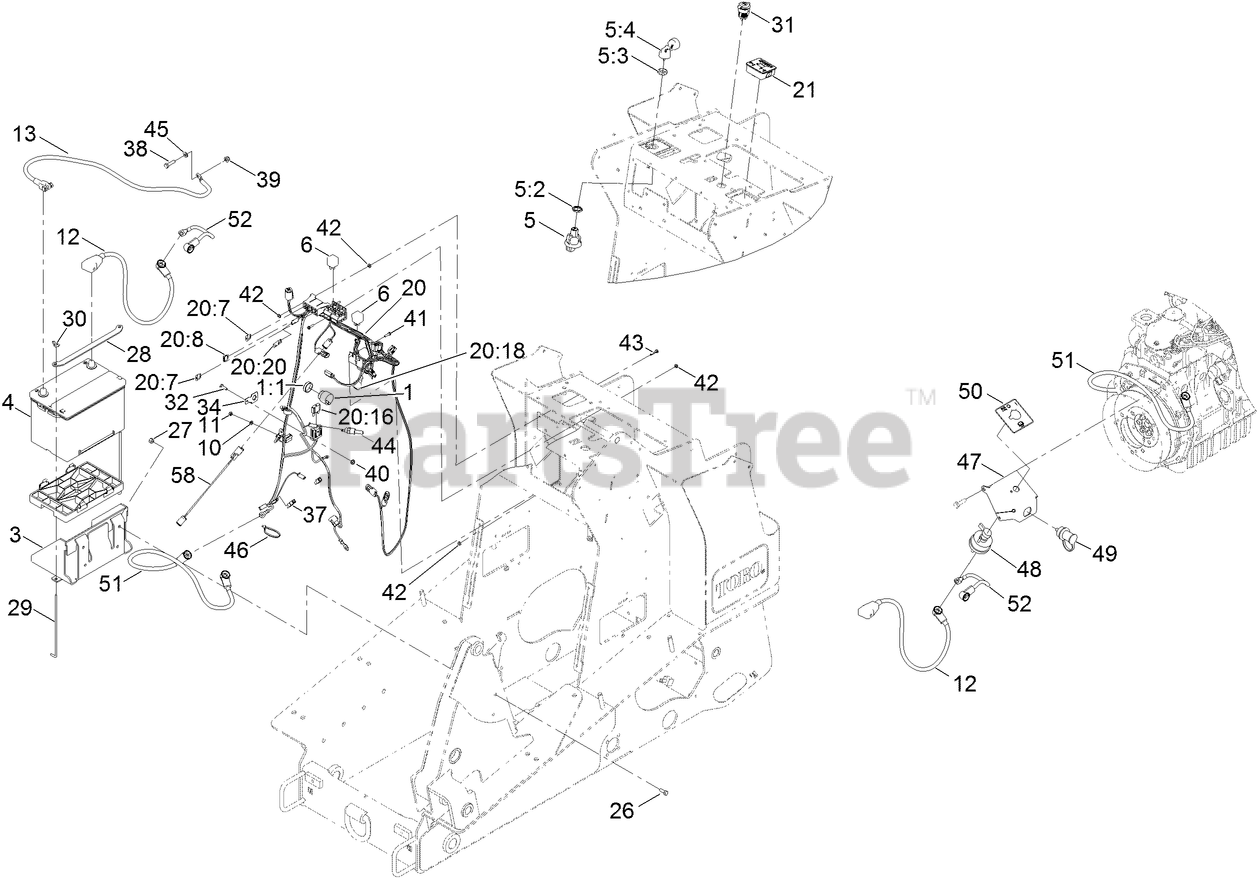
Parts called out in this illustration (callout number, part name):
1	AUDIO ALARM ASM
3	TRAY-BATTERY
4	BATTERY
5	IGNITION SWITCH ASM
5:2	NUT-HEX
5:3	NUT-FACE
5:4	SET-KEY, IGNITION
10	WASHER-LOCK, SPRING
11	NUT-HEX
12	CABLE-BATTERY, POS ASM
13	CABLE-NEGATIVE
20	HARNESS-WIRE
20:7	FUSE-BLADE, 10 AMP
20:8	FUSE-BLADE, 15 AMP
20:16	FUSE-BLADE, 50 AMP
20:20	CAP-PLUG
21	MODULE-HOUR METER
26	SCREW-HH
27	NUT-LOCK, NI
28	STRAP-HOLD DOWN, BATTERY
29	ROD-HOLD DOWN, BATTERY
30	NUT-WING
31	RECEPTACLE-12V
32	SCREW-HH
34	CLIP-FUSE
37	HARNESS-LINK, FUSIBLE
38	SCREW-HH
39	NUT-HF, NI
40	NUT-HF
41	SCREW-HWH
42	NUT-KEPS
43	SCREW-HWHTF
44	SWITCH-TEMP
45	WASHER-PLAIN
46	TIE-CABLE
47	MOUNT-REMOTE TERMINAL
48	SWITCH-DISCONNECT, MASTER
49	STUD-JUMPER, POSITIVE
50	DECAL-BATTERY DISCONNECT
51	CABLE-BATTERY, POSITIVE
52	CABLE-BATTERY, POSITIVE
58	HARNESS-WIRE
